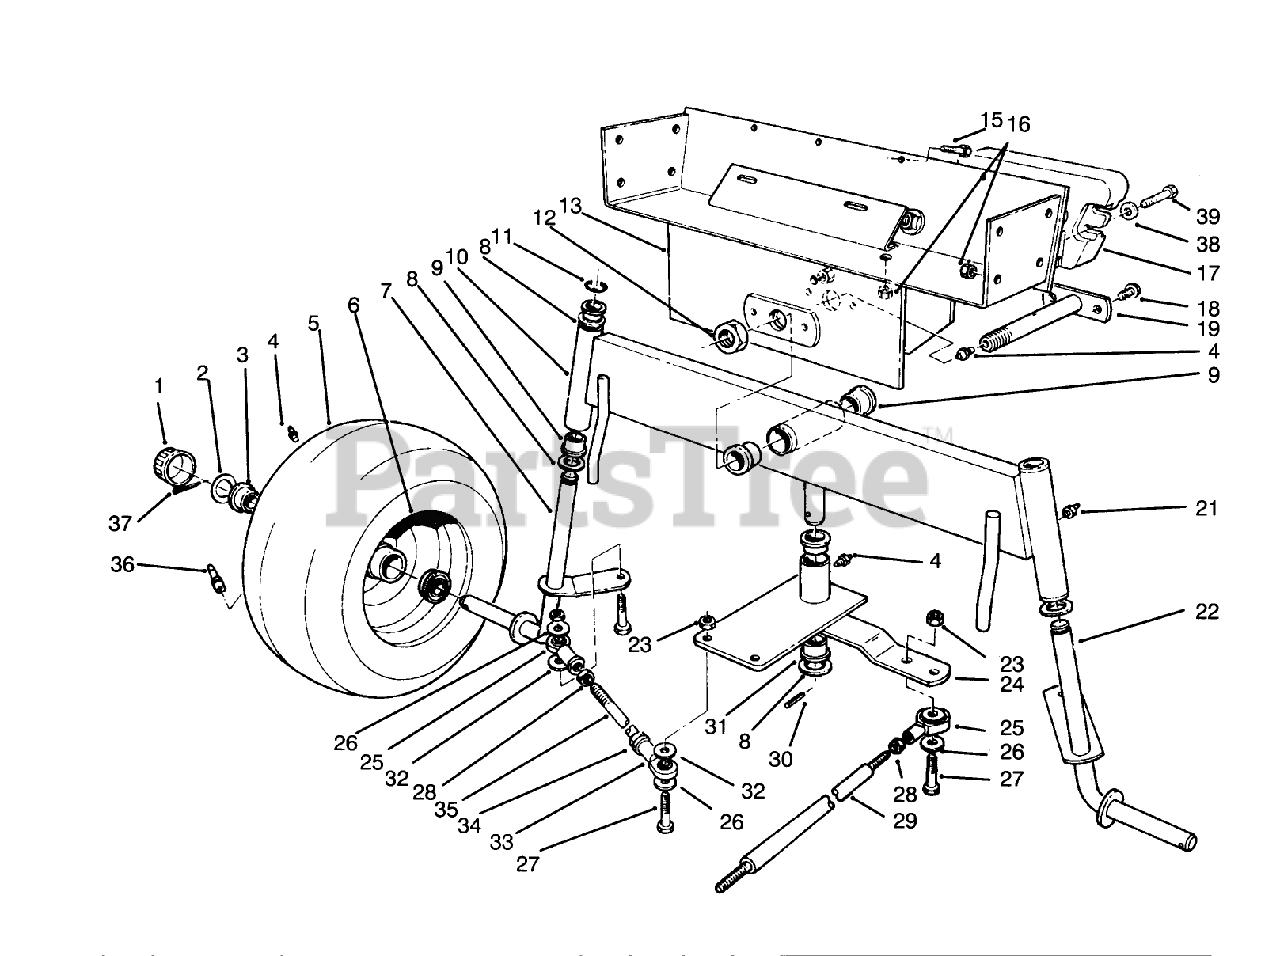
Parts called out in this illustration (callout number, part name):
1	CAP-HUB
2	WASHER-PLAIN
3	Bearing
4	FITTING-GREASE
6	FRONT WHEEL
7	Spindle R.H.
8	WASHER-THRUST
9	BUSHING PM
10	Axle-Rear (Incl. Ref. #9 & 20)
11	E-RING
12	NUT-LOCK NI
13	Frame-Rear
15	SCREW-HH
16	NUT-LOCK, NI
17	WEIGHT-REAR
18	SCREW-HHFTF
19	Axle-Pivot
21	GREASE FITTING
22	Spindle LH.
23	NUT-HEX
24	Plate-Pivot (Incl. Ref. #4 & 30)
25	BALL JOINT RH
26	WASHER-FLAT
27	SCREW-HH
28	NUT-JAM
29	Rod-Steering
30	PIN-ROLL
31	BEARING-FLANGE
32	WASHER
33	BALL JOINT LH
35	TIE ROD - STEERING
36	STEM-VALVE
37	PIN-COTTER
38	SCREW-HH
39	WASHER-LOCK
